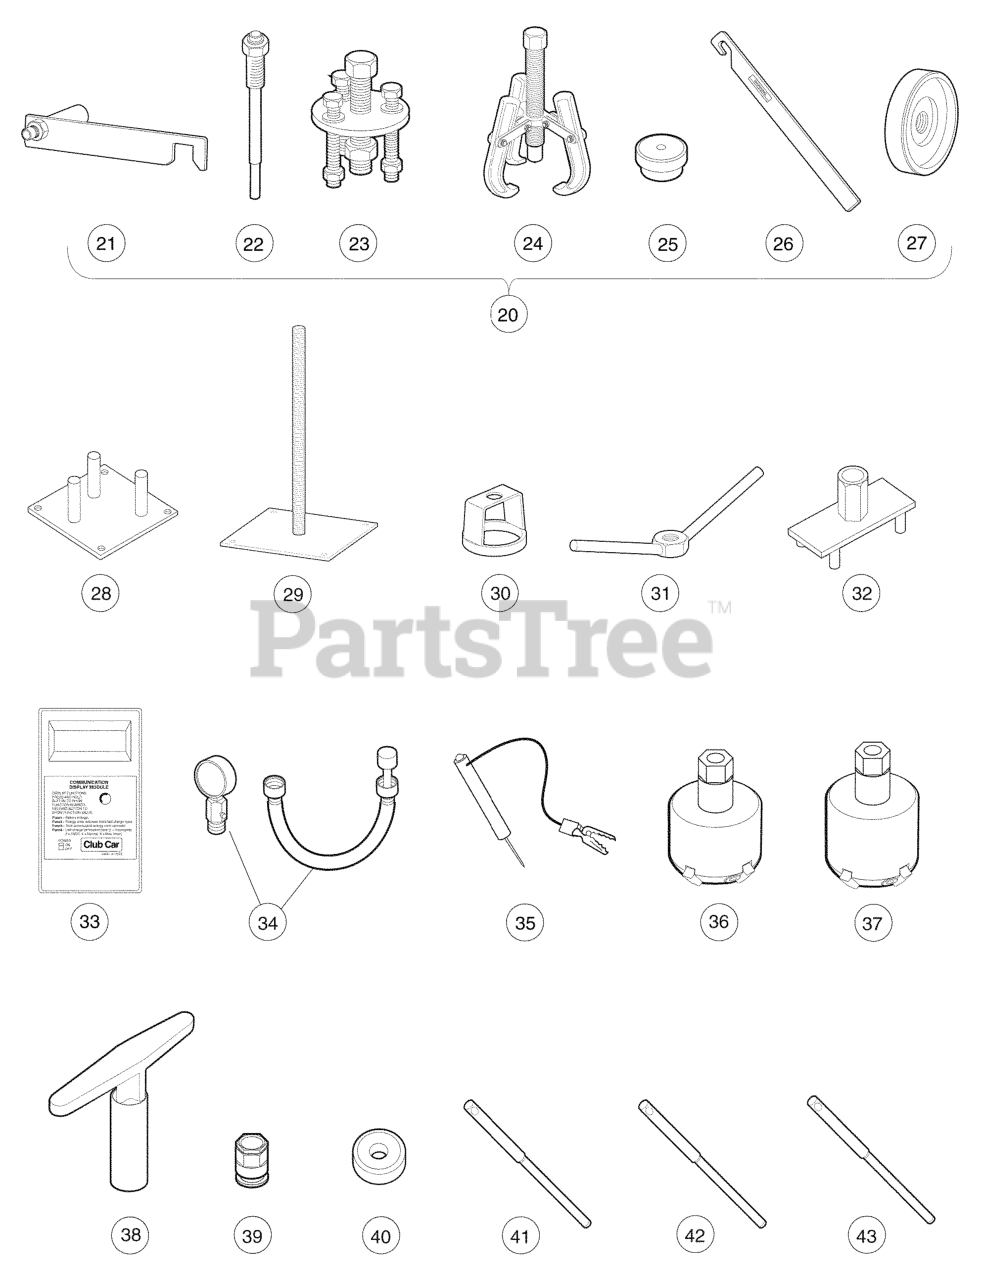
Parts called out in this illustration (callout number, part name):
1	TOOL, ACCEL. PEDAL ADJUSTMENT
2	GUIDE RING ADHESIVE 3 GRAMS
4	BATTERY DISCHARGE UNIT 36/48V
5	BATTERY TERMINAL PROTECT SPRAY
6	BATTERY THERMOMETER
7	BEAR & OIL SEAL REMOVER ASM
8	BEARING DRIVER SET
9	BEARING PULLER
10	BEARING PULLER WEDGE ATTACH.
11	BRAKE ADJUSMENT SOCKET TOOL
12	BRAKE CABLE RELEASE TOOL
13	Brake Pedal Adjustment Tool Kit
14	Brake Pedal Adjustment Tool
15	Brake Pedal Tension Tool
16	CALIBRATION & TEST MODULE
17	CAM INSTALLATION TOOL
18	CHARGER BEZEL TOOL
19	TOOL, REMOVAL, CLUTCH, GAS/DSL
20	C.C. CLUTCH TOOL KIT
21	TOOL, CLUTCH ALIGNMENT
22	TOOL, CLUTCH PULLER
23	CLUTCH DRIVE HUB PULLER
24	DRIVEN CLUTCH CAM PULLER
25	DRIVEN CLUTCH PULLER PLUG
26	DRIVE CLUTCH HOLDER TOOL ASM.
27	PRESS WELDMENT
28	TOOL-STATIONARY PRIMARY
29	TOOL-SPRING COMPRESSION BASE
30	TOOL-SPRING COMPRESSION COLAR
31	TOOL-SPRING COMPRESSION COLAR
32	TOOL-SPIDER PRIMARY
33	COMMUNICATION DISPLAY MODULE
34	COMPRESSION GUAGE AND ADAPTER
35	CONTINUITY TESTER
36	CUTTER, VALVE SEAT, #122
37	CUTTER, VALVE SEAT, #115
38	ADAPTER, T-WRENCH
39	ADAPTER, T-WRENCH
40	Cutter, Valve Seat, 60 Degree (requires item 51)
41	PILOT, 6.6 MM
42	PILOT, 6.62 MM
43	PILOT, 6.65 MM
44	LUBRICANT 11OZ CAN SPRAY
45	FLYWHEEL PULLER KIT
46	GAUGE, CARB FLOAT LEVEL
48	INSERT TOOL, GOVERNOR SHAFT
49	ADJUSTER, HYDRAULIC BRAKE
50	HYDROMETER
51	INERNAL RETAINING RING PLIERS
52	KIT, IQDM, USER, SERIES II
53	KIT, IQDM, OEM, SERIES II
54	ADAPTER, 1307 CABLE
55	CABLE, IQDM, SERIES II
56	CABLE, IQDM
57	SEALANT
58	LUBRICANT, MOLY-TEFLON,4 OZ TU
59	TOUCH UP PAINT BEIGE
59	TOUCH UP PAINT, BLACK
59	TOUCH UP PAINT, BURGUNDY
59	TOUCH UP PAINT, CLASSIC BLUE
59	TOUCH UP PAINT, DARK GRAY
59	TOUCH UP PAINT, DARK GREEN
59	TOUCH UP PAINT, GRAY
59	TOUCH UP PAINT, RED
59	TOUCH UP PAINT, ROYAL BLUE
59	TOUCH UP PAINT, WHITE
60	PAINT, GRAY - SPRAY
61	PAINT PEN, UNDERBODY, BLACK
62	KIT, PISTON RING COMPRESSOR
63	PISTON RING PLIER
64	SPECIAL-USE PULLER SET
65	EXTERNAL SNAP RING PLIERS
66	INTERNAL SNAP RING PLIER 9O
67	SAFETY FIRST CARD
68	SEAL PULLER
69	WRENCH, SPANNER
70	Steering Column Bearing Press Tool
71	TOOL-STEERING RETAINING RING
72	PULLER, STEERING WHEEL
73	TACHOMETER GAS/DIESEL
74	TACHOMETER DIESEL ADAPTOR
75	TRANS-AXLE, AXLE SEAL TOOL
76	Transaxle Pinion Seal Tool
77	Transmission Tool Kit
82	VALVE CLEAR ADJ SCREW HOLDER
83	DRIVER, VALVE GUIDE, 6.6. MM
84	VALVE GUIDE REAMER
85	REAMER-VALVE GUIDE
86	VALVE SEAT CUTTER GUIDE
87	VALVE SEAT CUTTER "T" WRENCH
88	VALVE SEAT CUTTER 45 DEG 32 MM
89	CUTTER INTAKE VALVE ST 45/30
90	VALVE SPRING CMPR & ADAPTER
91	METER, WAVETEK VOLT-OHM
92	S/G TENSIONING TOOL
